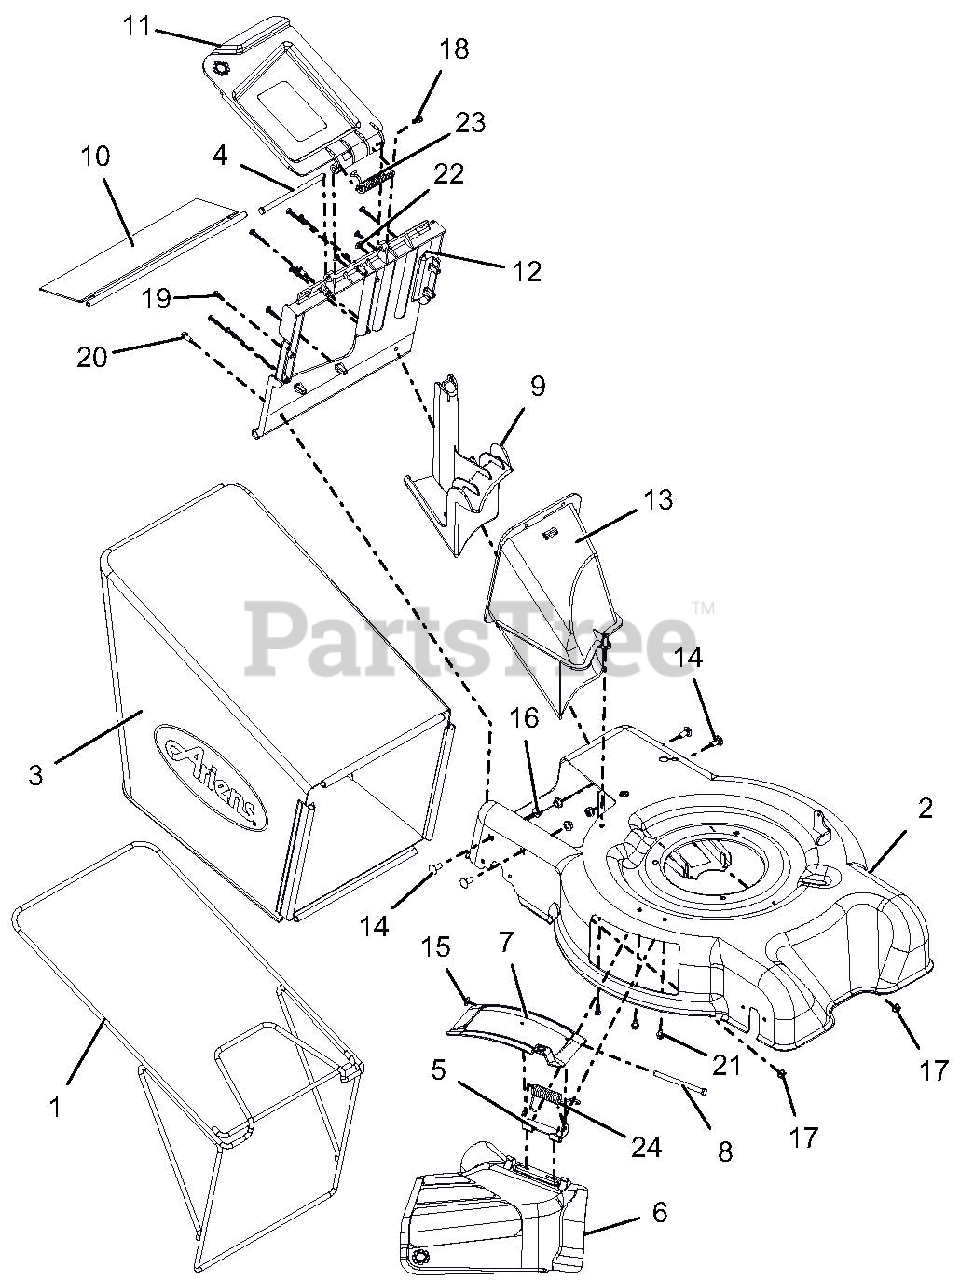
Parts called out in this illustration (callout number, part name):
1	FRAME, BAG
2	DECK, RAZOR W/ SAFETY DECALS
3	BAGGER, ARIENS LM
4	PIN, 5/16 X 5.80"
5	BRKT, HINGE LM
6	CHUTE, SIDE DISCHARGE - LM
7	COVER, SIDE DISCHARGE - LM
8	PIN, HINGE
9	PLUG, MULCH
10	GUARD, REAR DECK
11	REAR DOOR W/ SAFETY DECAL
12	HANGER, REAR BAG
13	CHUTE, REAR DISCHARGE LM
14	@BLT-RDHDSQNK .31-18X.75 G5YZ
15	NUT-PUSH .312
16	@NUT-LK-TOP-FLG .31-18 YWZC
17	@NUT-LK-TOP-FLG .25-20 YWZC
18	PIN-HAIR INT .08X.18X1.18 YWZC
19	SCR-TAP 12-14X.75PLSTITE @BLZC
20	@SCR-TAP .25-20X.62 HWH TR YWZ
21	@SCR-TAP .25-20X.37 HWH YWZ TR
22	PLUG,5/16 HOLE,.125 MATL PLSTC
23	SG-TORS .120X.68X3.09
24	SPRING, SIDE DISCHARGE DOOR
